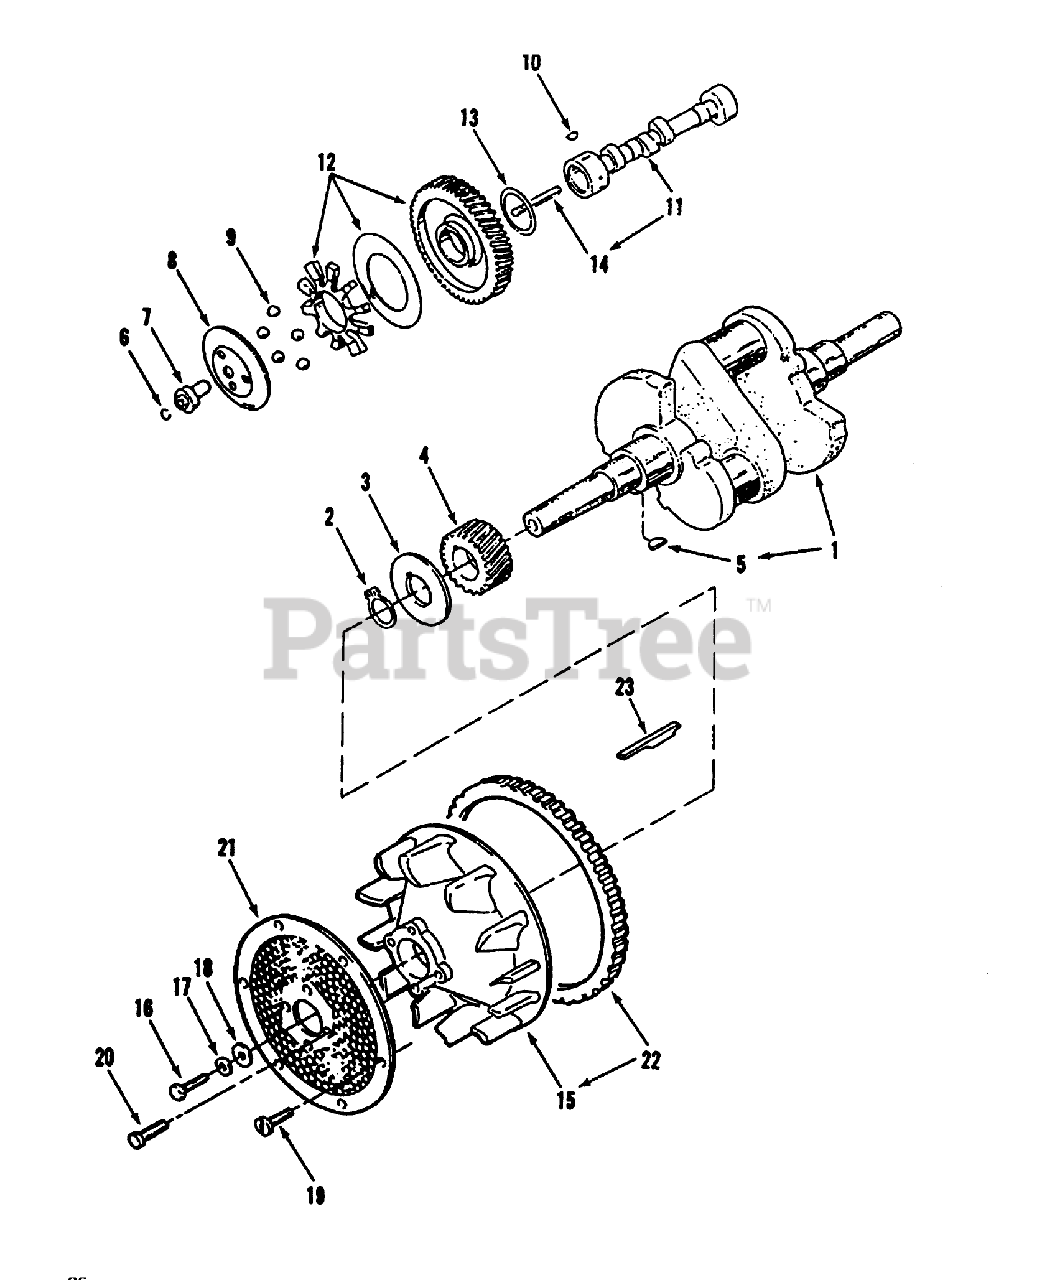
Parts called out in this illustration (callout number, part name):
9	BEARING
17	WASHER-FLAT
21	SCREEN-AIR INLET
23	KEY - MACHINE
